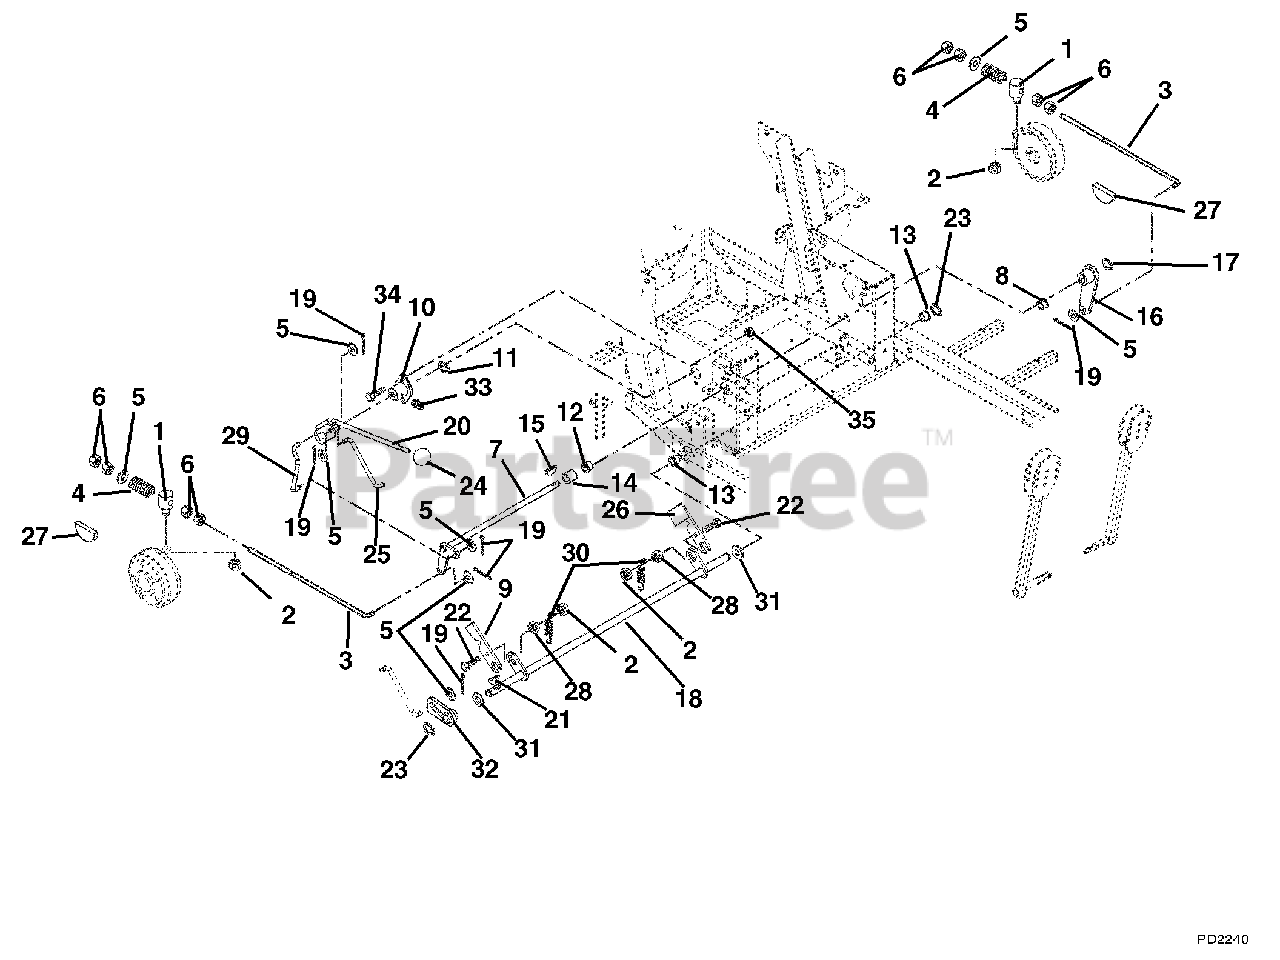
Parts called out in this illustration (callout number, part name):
1	Pivot-Brake Rod
2	Nut-Locking-Center .31-18
3	PTO Link Rod
4	Spring-Compression .143 x .710 x 2.00
5	Washer-Flat-Steel .406 x .812 x .065
6	Nut-Hex .38-16
7	Shaft-Brake Cross
8	Bushing-Flange Nylon .63 x 1.00 x .625
9	Slide, Interlocking Brake
10	Bushing, Flange
11	Ring-Retaining-External .625 x .05
12	Bushing-Flange Nylon .762 x 1.00 x .58 x 1.48
13	Bushing-Flange .50 x .75 x .75 x 1.00
14	Bushing-Sleeve .75 x 1.00 x .75
15	Key-Woodruff .19 x .75 Hard #9
16	Arm-Brake Left-Hand
17	Ring-Retaining-External .625 x .050
18	Weldment, Mechanical Brake
19	Pin-Cotter External .09 x .75
20	Shaft-Brake Actuating
21	Key-Woodruff .13 x .63
22	Bolt-Hex .31-18 x 1.25 Grade 5
23	Ring-Retaining-External .50 x .05
24	Knob, Steering Lock
25	Linkage, Brake Actuating
26	Interlock, Safety Switch
27	Pad, Disk Brake
28	Nut-Locking-Top-Flange .31-18
29	Linkage, Brake Actuating
30	Spring-Tension .048 x .44 x 1.75
31	Washer-Flat-Steel .505 x 1.00 x .062
32	Weldment, Parking Brake Hub
33	Fitting-Lube .25-28 x .256
34	Bolt-Hex .31-18 x .75 Grade 5
35	Nut-Locking-Nylon .312-18
